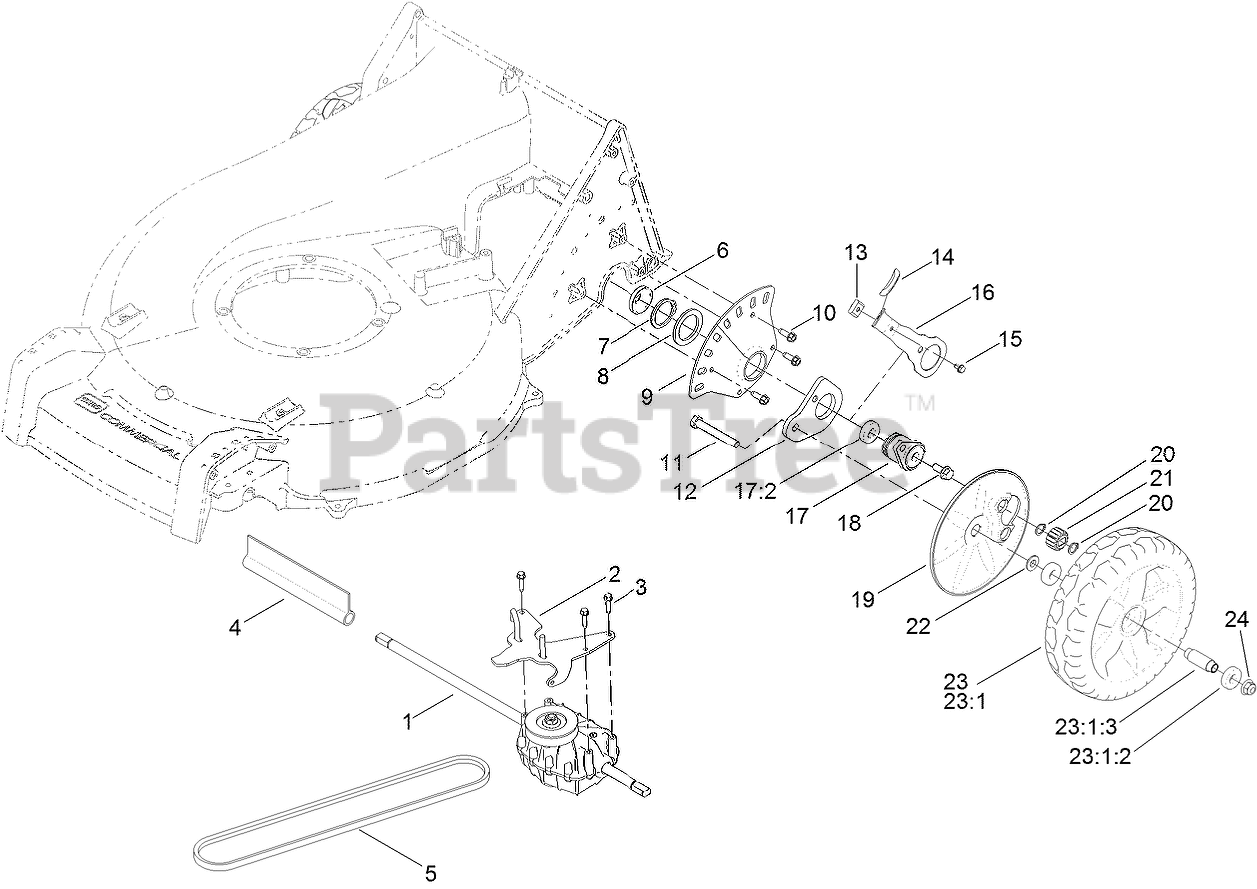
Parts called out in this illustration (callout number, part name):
1	TRANSMISSION
2	GUIDE-BELT
3	SCREW-SPECIAL
4	COVER-SHAFT, TRANSMISSION
5	BELT-V
6	COVER-BEARING
7	RING-RETAINING
8	Washer-Thrust
9	PLATE-HOC, REAR
10	SCREW-HWHTF
11	SCREW-HH
12	ARM-PIVOT, REAR
13	KEY-ARM, SPRING
14	KNOB-LEVER, HOC
15	SCREW-HWH
16	ARM-SPRING, REAR
17	BEARING RETAINER ASM
17:2	BEARING-BALL
18	SCREW-HWH
19	COVER-WHEEL
20	RING-RETAINING
21	GEAR-PINION, 15T
22	SPACER-COVER, WHEEL
23	WHEEL ASM
23:1	WHEEL
23:1:2	BEARING-BALL
23:1:3	SPACER
24	NUT-HF, NI
